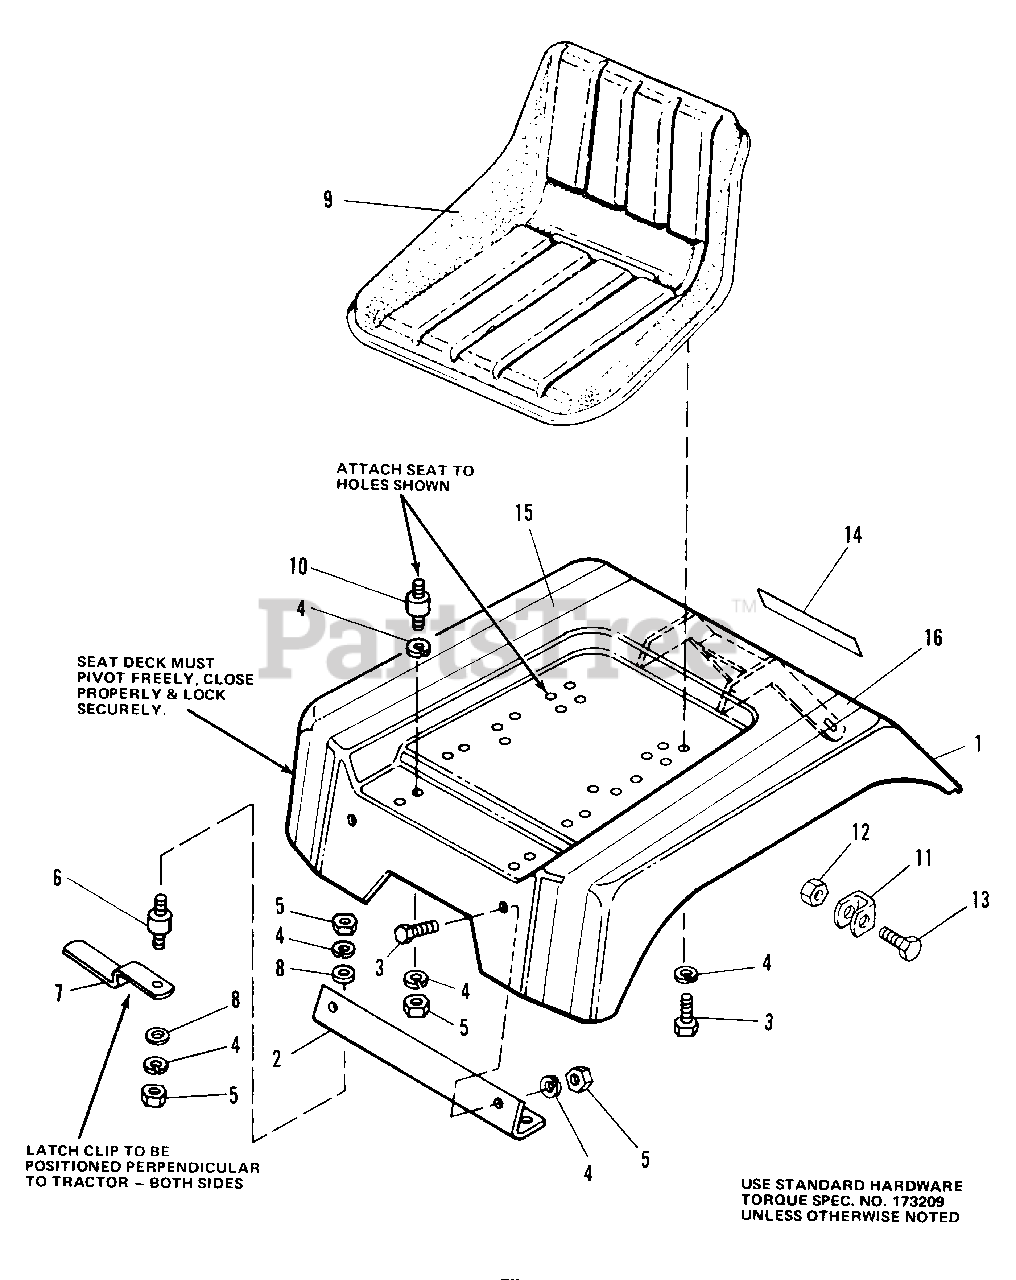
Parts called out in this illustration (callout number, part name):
1	SEAT, Deck
2	BRACKET, Frt. Seat Deck
3	CAPSCREW, 5/16-18 x 5/8
4	LOCKWASHER, 5/16
5	NUT, Hex, Full, 5/16-18
6	CONNECTOR, Cushion
8	WASHER, 1/4
10	CONNECTOR, Cushion
11	STOP, Seat Deck
12	LOCKNUT, Hex, 3/8-16
13	CAPSCREW, Hex, 3/8-16 x 1-1/4
14	DECAL, Simplicity
15	DECAL, Stripe, R.H. (1690232 & 1690233 Only)
16	DECAL, Stripe, L.H. (1690232 & 1690233 Only)
